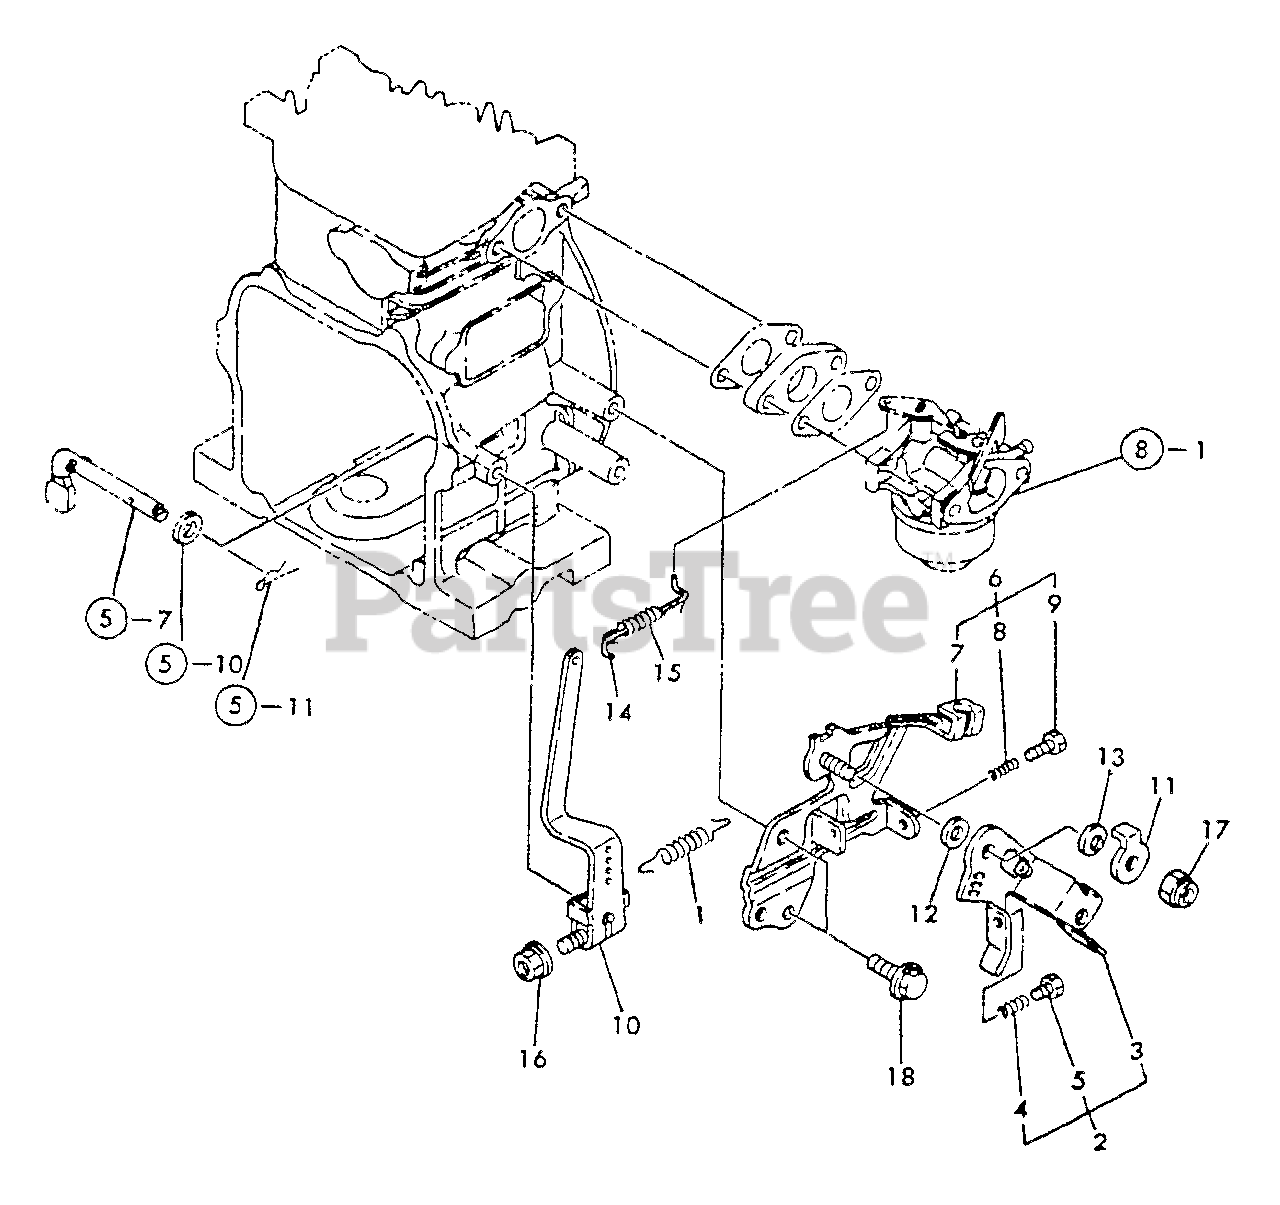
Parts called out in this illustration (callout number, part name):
1	SPRING, REGULATOR
2	HANDLE ASSY, REGULATOR
3	HANDLE, REGULATOR
4	SPRING, IDLE
5	BOLT - 4×20
6	BASE ASSY, REGULATOR
7	BASE, REGULATOR
8	SPRING, IDLE
9	BOLT - 4×25
10	LEVER, COVER
11	WASHER
12	WASHER - NYLON
13	SPRING, PLATE
14	LINK, THROTTLE
15	SPRING, THROTTLE
16	U-NUT M6
17	NUT - 6
18	BOLT - 6×8 -- PLATED
